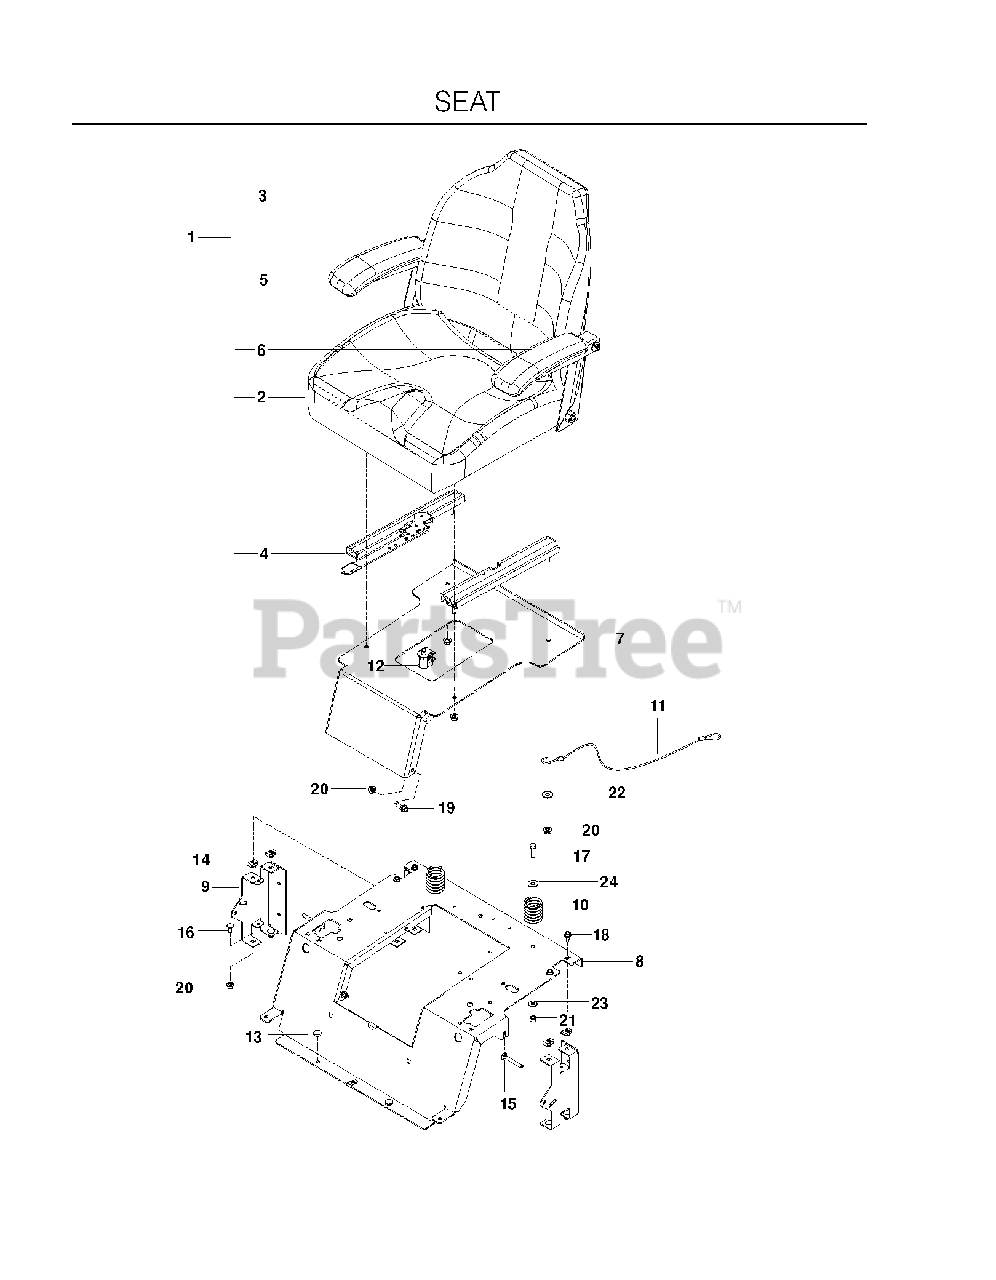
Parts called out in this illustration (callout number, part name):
1	SEAT, 907 DIXON
4	4"SINGLE LOCK TRACK SET W/HDWR
5	BLACK SELFSKIN-ARM PAD ONLY
6	LEFT SELFSKINNED 907 ARM W/BRK
7	WLDMT, SEAT PAN, BLUE
10	SPRING, SEAT
11	SEAT LANYARD
12	SEAT SWITCH
13	GROMMET, BUMPER
14	U-CLIP 5/16-18 NUT RETAINER
15	RHSNB 5/16-18 X 2-1/2 GR5 ZD
16	BOLT 5/16C X 3/4" CARRIAGE
17	HCS 3/8C X 1 1/4
18	BOLT 5/16-18 X 3/4
19	SB 5/16-18 HEX HD GD5, BLK ZN
20	5/16-18 NYLOC FLANGE NUT
21	NUT 3/8-16 NYLOC
22	WASHER 5/16 FLAT
23	WASHER 3/8 SAE FLAT
24	WASHER 3/8 FLAT
